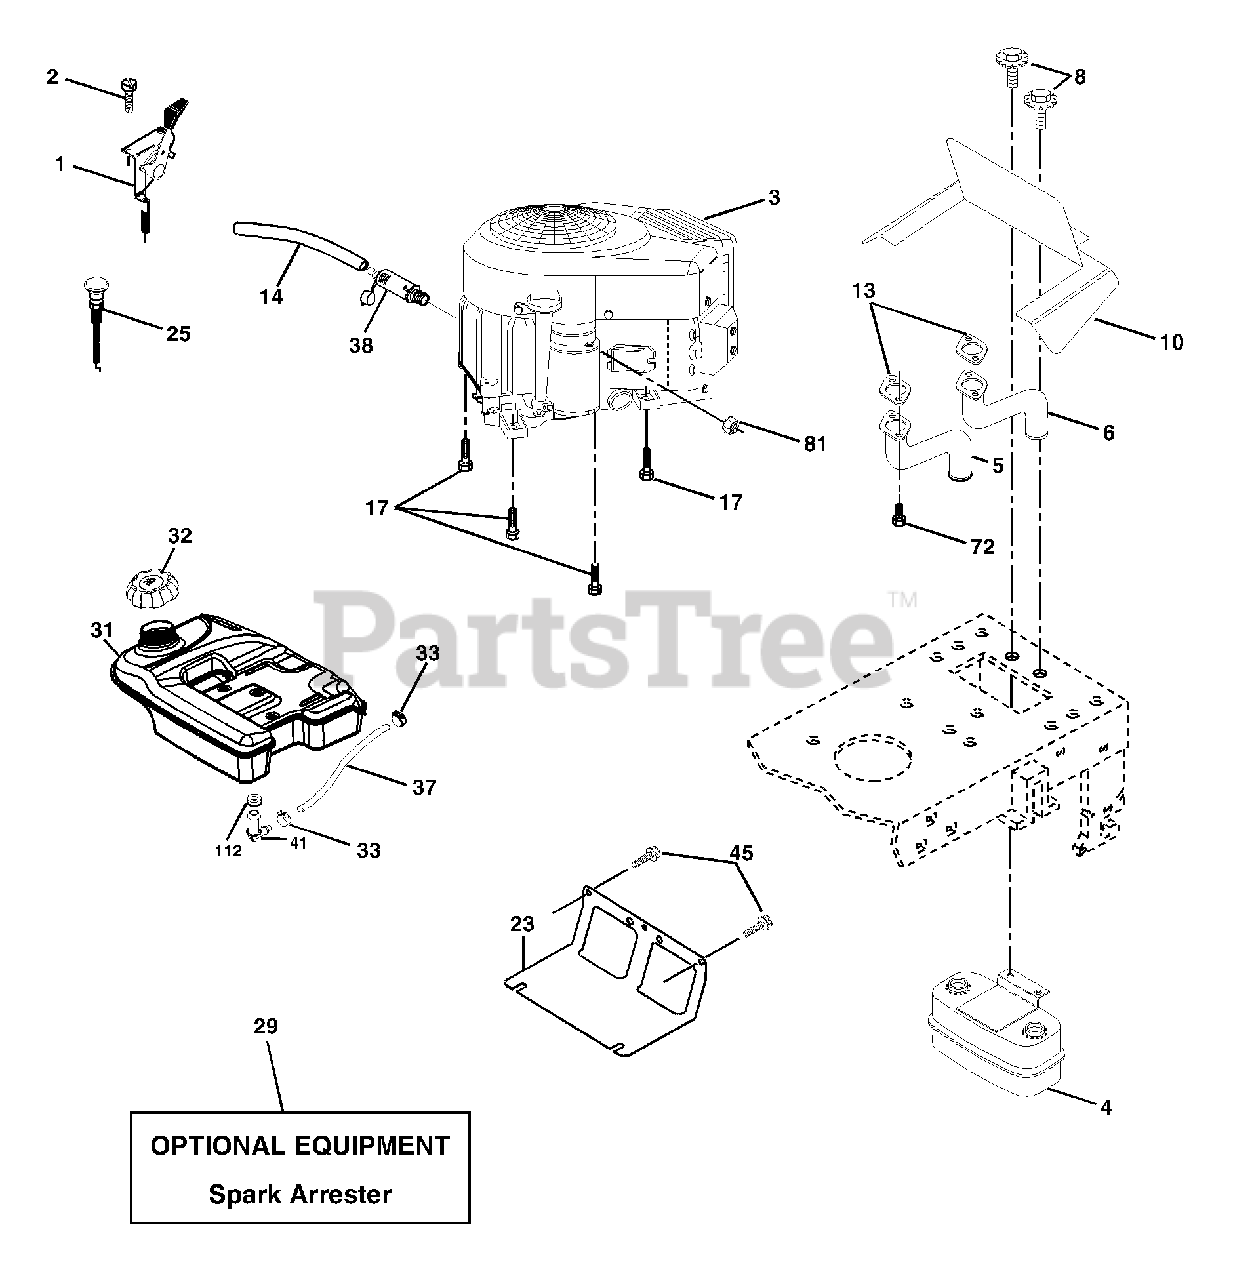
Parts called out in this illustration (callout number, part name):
1	Control, Throttle
2	Screw Hex Thd Cut 1/4-20 x 1/2
4	Muffler, Asm. Twin Lo-Tone
5	Pipe Exhaust Intek 20 RH
6	Pipe Exhaust Intek 20 LH
8	Bolt 5/16-18 unc x 3/4 w/Sems
10	Shield Browing B&S Intek II
13	Muffler Gasket
14	Tube Oil Drain
17	Screw 3/8-16 x 1-1/2
23	Shield, Browning/Debris Guard
29	Arrester, Spark
31	Tank, Fuel
32	Cap Gauge, Fuel
33	Clamp, Hose Blk
37	Line, Fuel
38	Plug Drain Oil Easy
41	Stem Tank Fuel
45	Screw Hex Wsh Thdrol 3/8-16 x 3/4
72	Screw Socket Head 5/16-18 x 1
81	Nut Keps Hex 1/4-20 unc
112	Bushing
